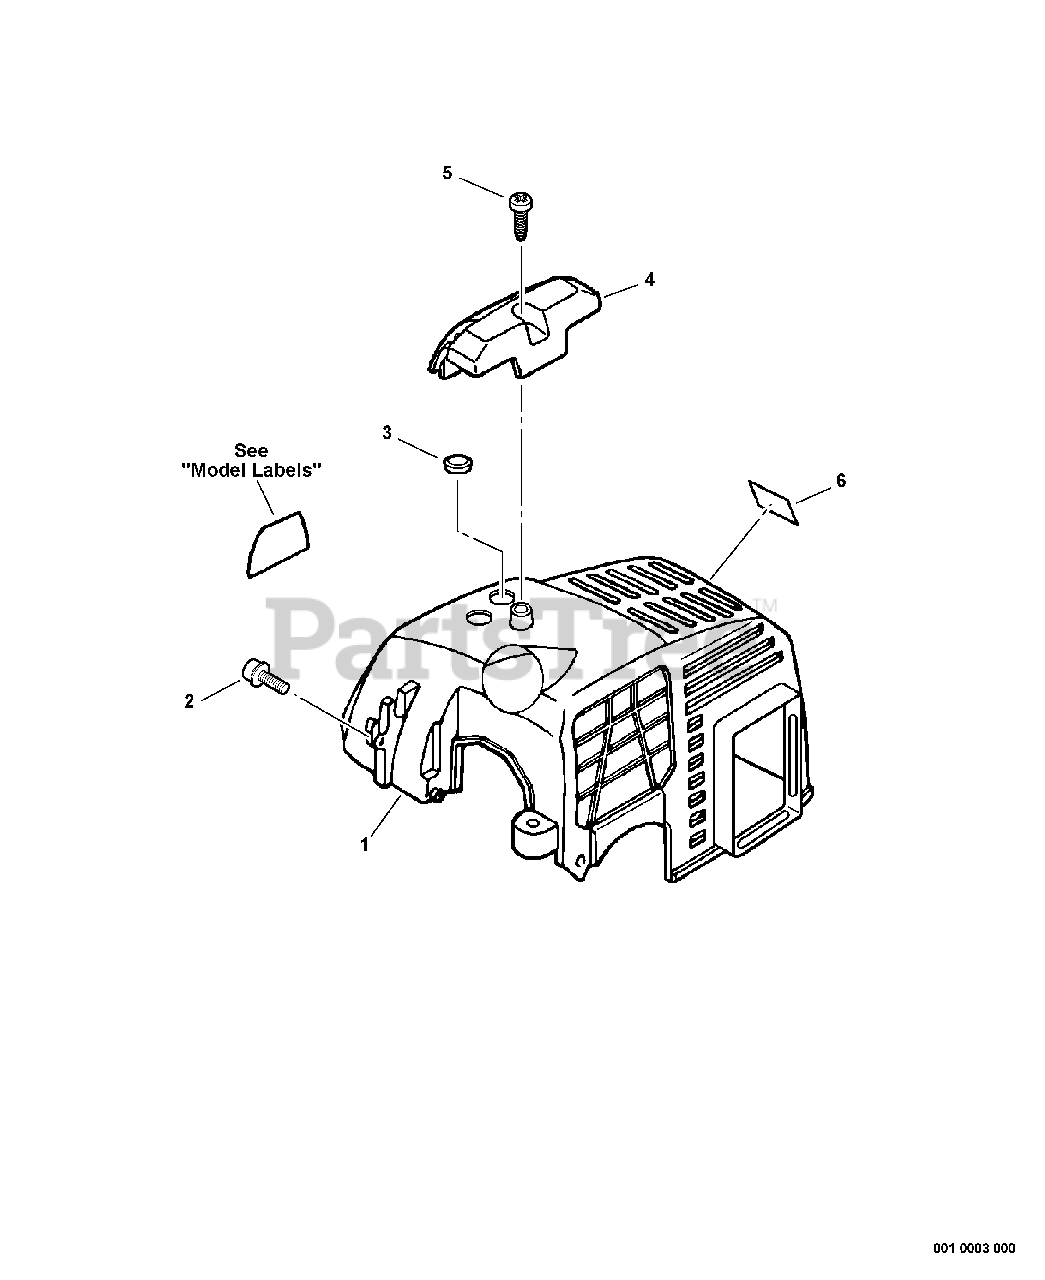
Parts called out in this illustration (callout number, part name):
1	COVER, ENGINE
2	SCREW 4×12
4	GUARD, TOP - GRAY
5	SCREW 5×16
6	LABEL, CAUTION - HOT
